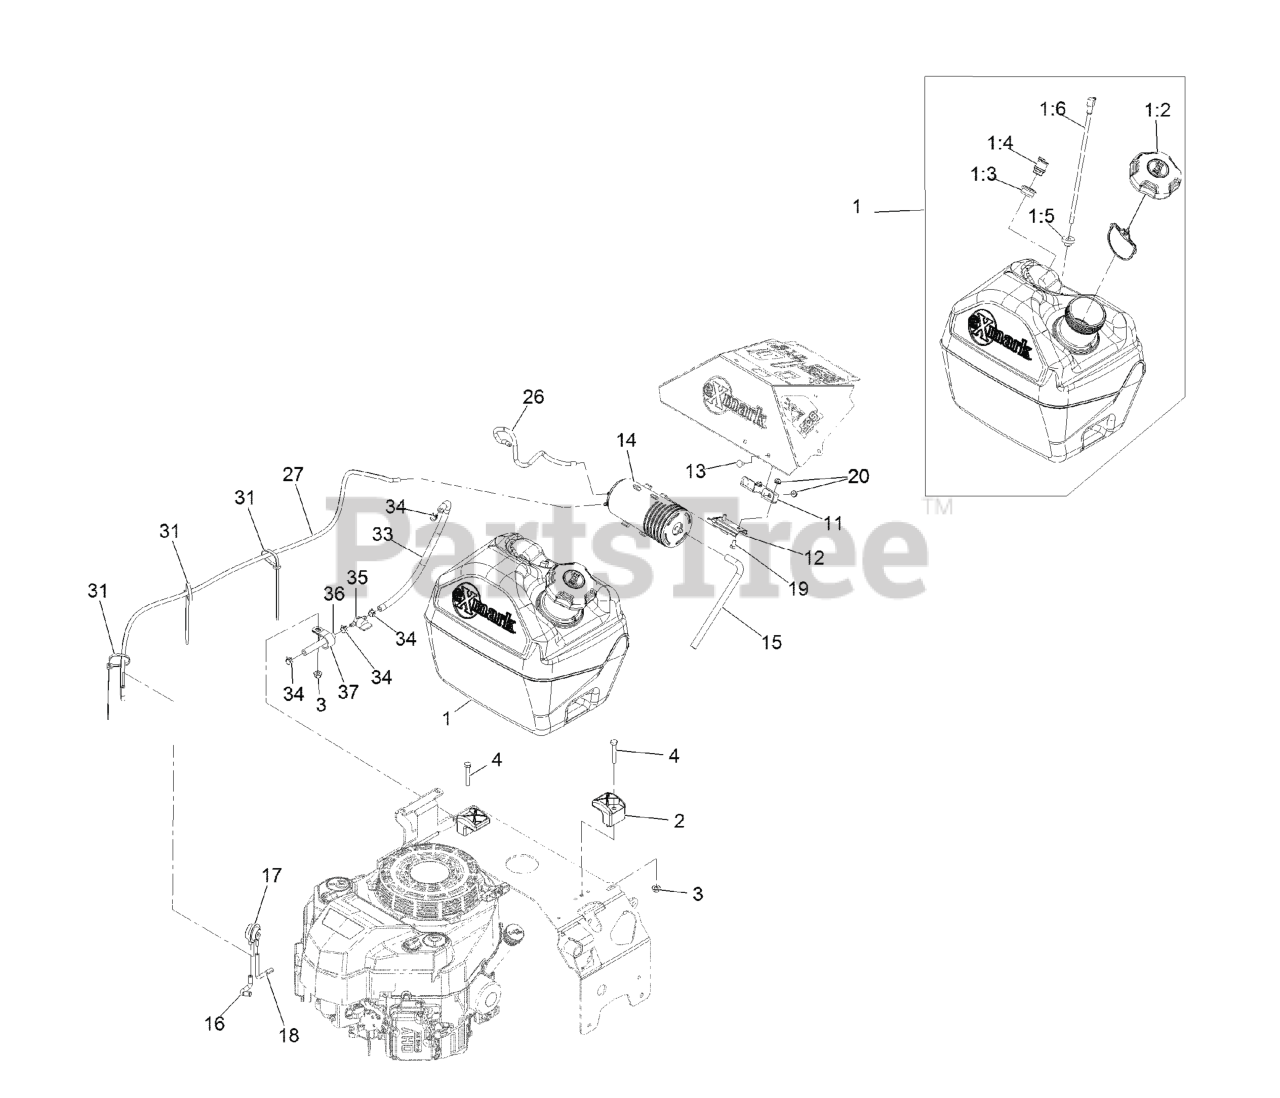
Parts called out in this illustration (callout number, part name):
1	ASM, FUEL TANK 5 GAL
1:2	CAP-FUEL, RATCHETING
1:3	GROMMET
1:4	VALVE-VENT, FUEL
1:5	BUSHING
3	NUT-HF, NI
4	SCREW-HH
11	BRACKET-CANISTER, CARBON
12	BRACKET-CANISTER, CARBON
13	SCREW-CARR
14	CANISTER-CARBON, 800CC
15	HOSE-VENT, CANISTER
16	HOSE-VENT, FORMED
17	VALVE-CONTROL, VACUUM
18	HOSE-VENT, FORMED
19	SCREW-HH
26	HOSE-EMISSIONS
27	HOSE-VENT, FORMED
31	TIE-PLASTIC
33	HOSE-FUEL
34	CLAMP-HOSE
35	VALVE-FUEL
36	HOSE-FUEL
37	CLIP-LOOM
